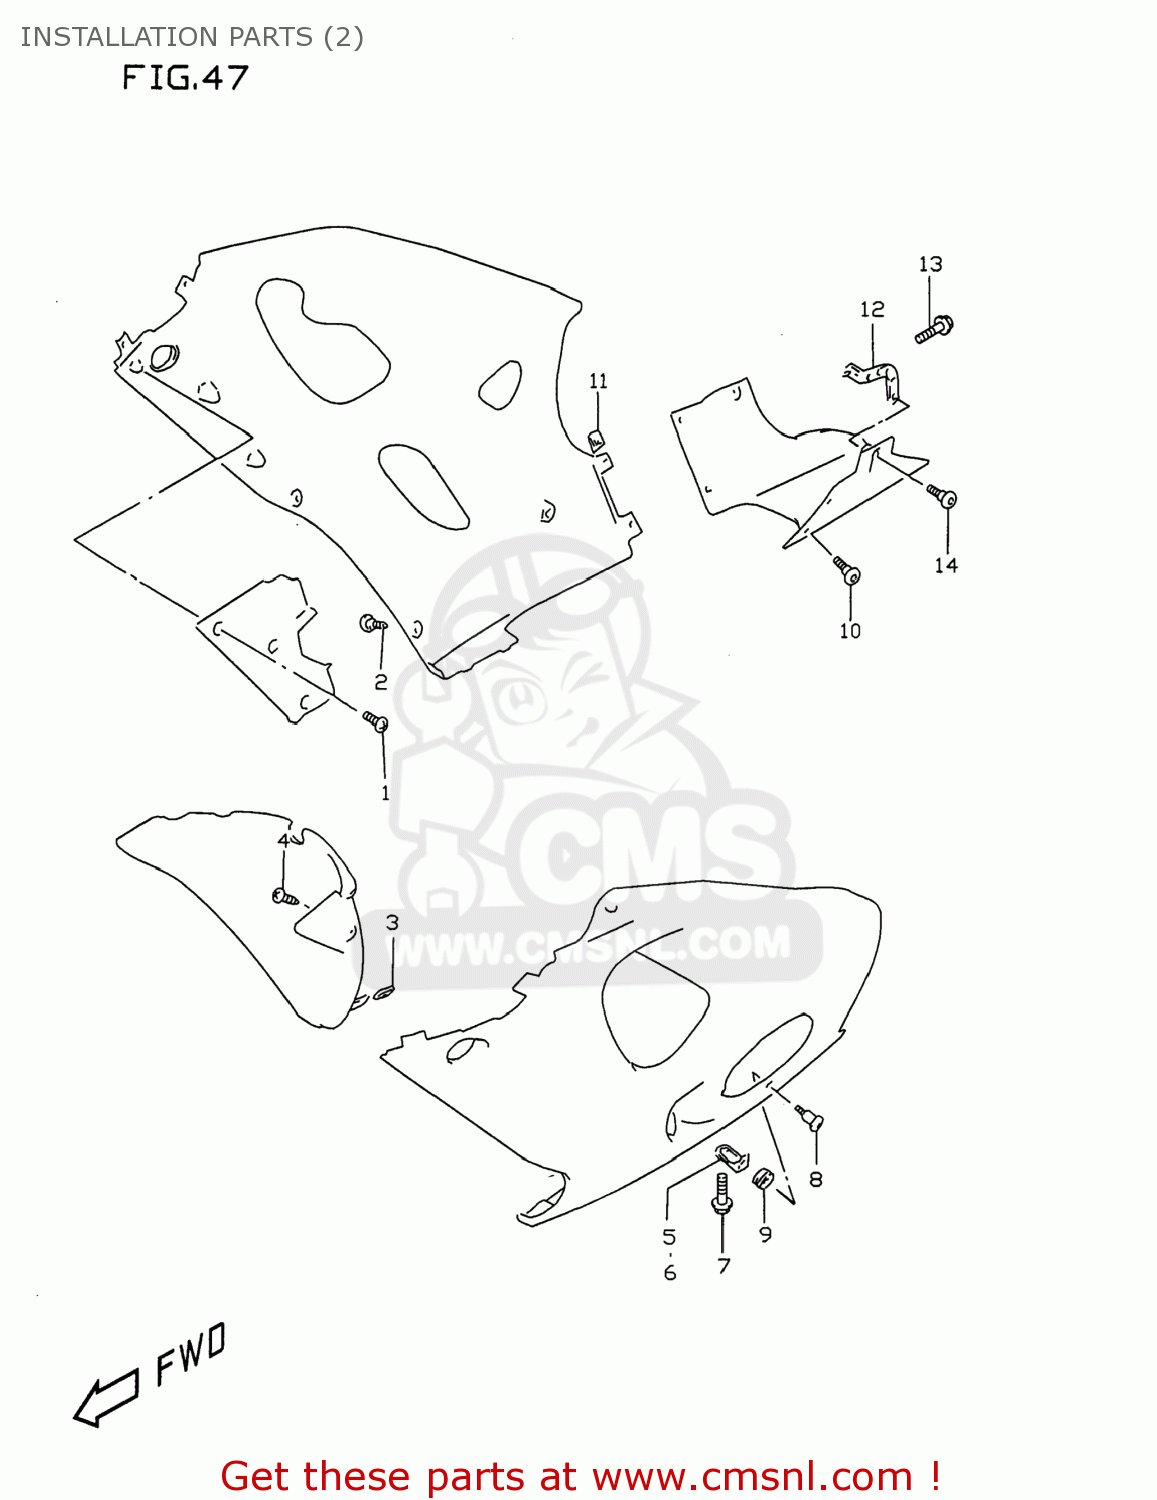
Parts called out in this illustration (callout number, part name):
1	SCREW
2	SCREW(5X16)
3	NUT,HEADLAMP HOUSING,UPPER
4	SCREW
5	BRACKET,UNDER COWLING,LOWER
6	BRACKET,UNDER COWLING,LOWER
7	BOLT
8	SCREW(6X20)
9	CUSHION
10	SCREW(5X16)
11	NUT,HEADLAMP HOUSING,UPPER
12	BRACKET,RR UNDER COWLING
13	BOLT
14	SCREW(5X16)
